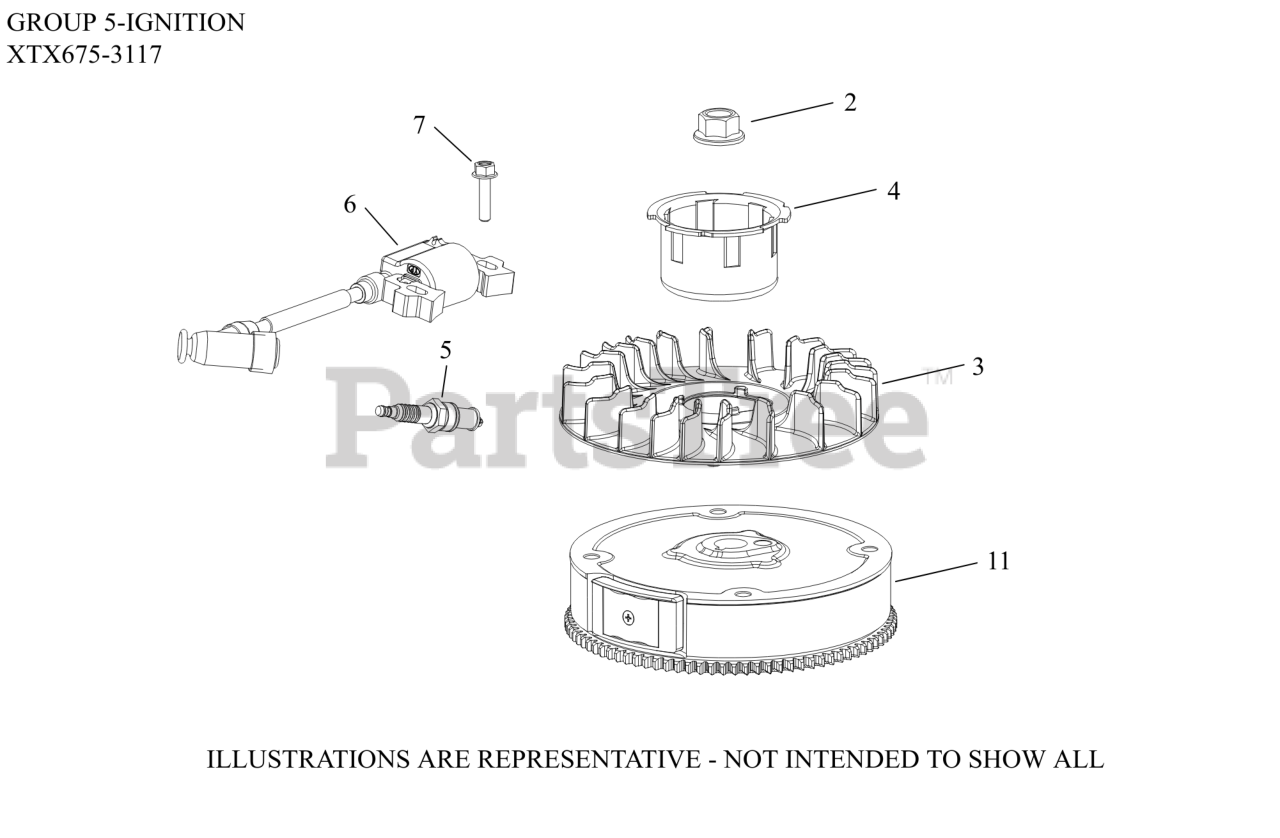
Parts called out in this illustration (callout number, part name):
2	NUT, FLYWHEEL (W/SERRATIONS)
3	FAN, FLYWHEEL
4	CUP, STARTER DRIVE
5	PLUG SPARK 12MM RFI
6	MODULE IGN (#1458416S)
7	SCREW, M6 X 25-(#25086436S)
11	FLYWHEEL ASSY, ELECTRIC START
